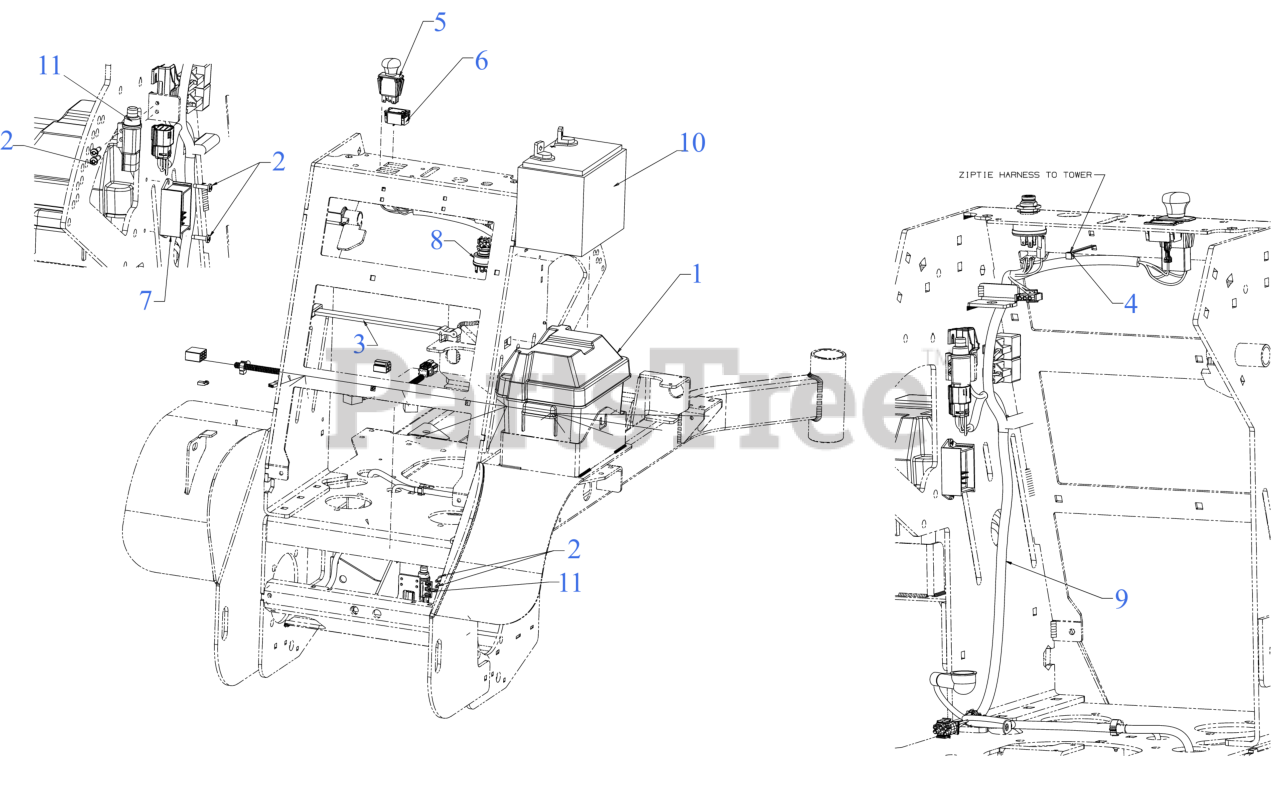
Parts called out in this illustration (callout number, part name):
1	BATTERY CONTAINER
2	SCREW (10-24X.75:PH:TAP:T25:GR5)
3	BATTERY RETAINER STRAP
4	7" CABLE TIE
5	PTO SWITCH (BLACK KNOB) TEXT SYM
7	CONTROL PANEL (SOFT CLUTCH)
8	KEY SWITCH
10	BATTERY (230 CCA AGM U1-280)
11	SEALED PLUNGER SWITCH
